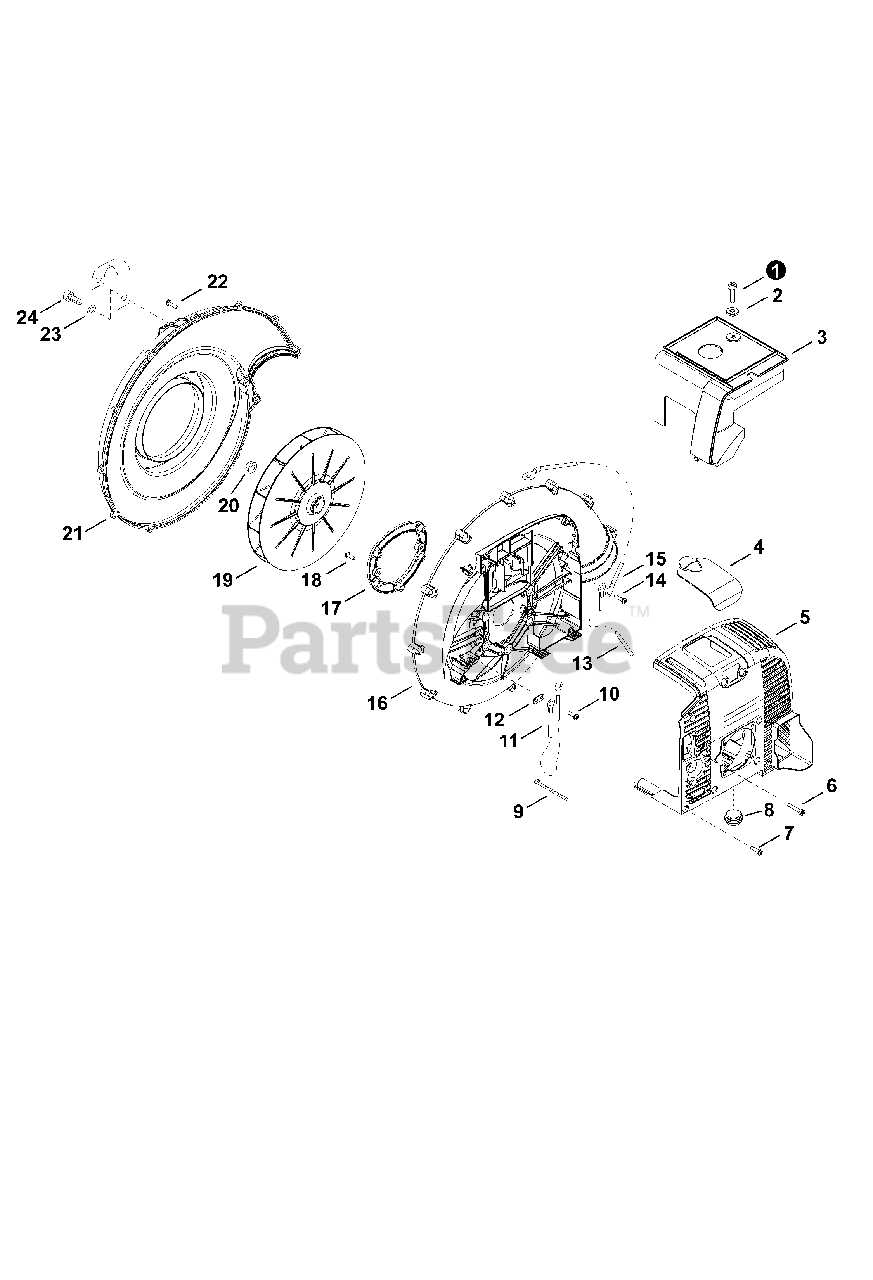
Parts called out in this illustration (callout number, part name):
1	BOLT 5×20
2	WASHER 5.2×14×T3
3	COVER, CYLINDER
4	COVER, SPARK PLUG
5	COVER, ENGINE
6	BOLT, TORX 5×16
7	BOLT, TORX 5×20
8	CUSHION
9	STRAP, TIE
10	BOLT, TORX 5×16
11	LEAD L= 295 MM
12	PLATE, EYE
13	WIRE, STATIC DISCHARGE 890 MM
14	BOLT, TORX 5×12
15	LEAD L= 195 MM
16	CASE, FAN
17	PLATE, ENGINE
18	BOLT, TORX 5×16
19	FAN, BLOWER
20	NUT, FLANGE 10×1.25
21	COVER, FAN
22	BOLT, TORX 5×20
23	WASHER 5.5×16×2T
24	BOLT, TORX 5×20
